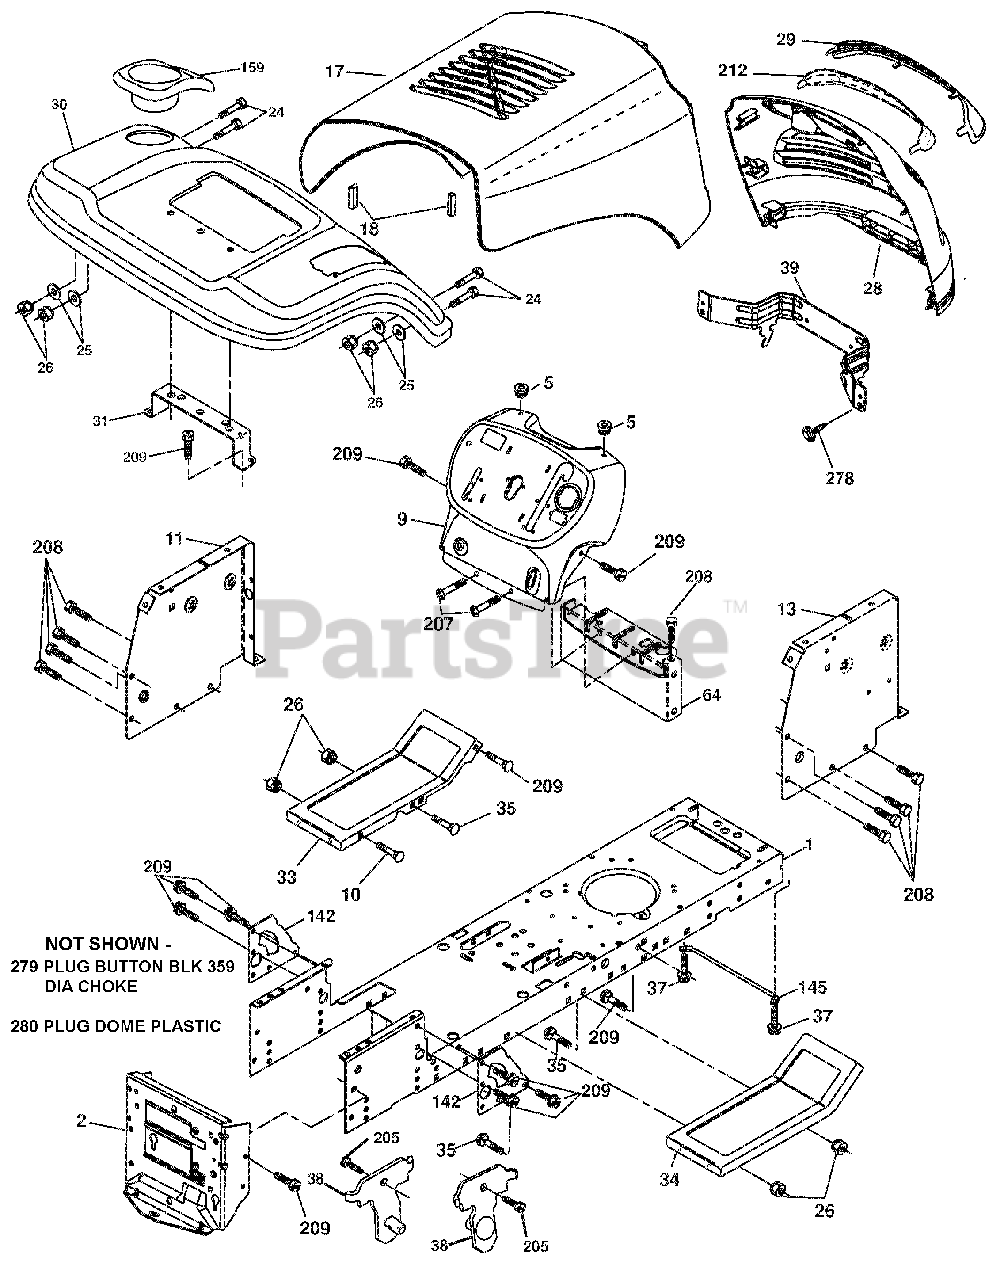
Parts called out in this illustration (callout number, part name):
1	Chassis
2	Drawbar, Stretch
5	Bumper, Hood/Dash
10	Bolt, Carriage 3/8-16 x 1
11	Panel Dash LH
13	Panel Slkscr Dash RH
18	BUMPER.HOOD.LARGE. 1.75"
24	Bolt Fin Hex 3/8-16 unc x 1 Gr
25	Washer 13/32 x 13/16 x 12 Ga.
26	Locknut, Washer Insert 3/8-16
28	Grille
29	Lens Grille Bar
31	Bracket Fender Repl 109873X
33	Footrest Pnt LH
34	Footrest Pnt RH
35	Bolt Rdhd Sht Sqnk 3/8-16 x 3/
37	SCREW.THDROL.5/16-18 X 1/2TYTT
38	Bracket Asm. Pivot Mower
39	Bracket Pivot
64	Dash Lower
142	Plate Reinforcement
145	ROD.PIVOT.HOOD
159	Cupholder
205	Screw Thdrol 3/8-16 x 1/2
207	Screw 5/16-18 x 1/2
208	SCREW.THDROL.3/8-16X1/2.TYT.BL
209	SCREW.HEXWSH THDR3/8-16X3/4.BL
212	Insert Lens Reflect
